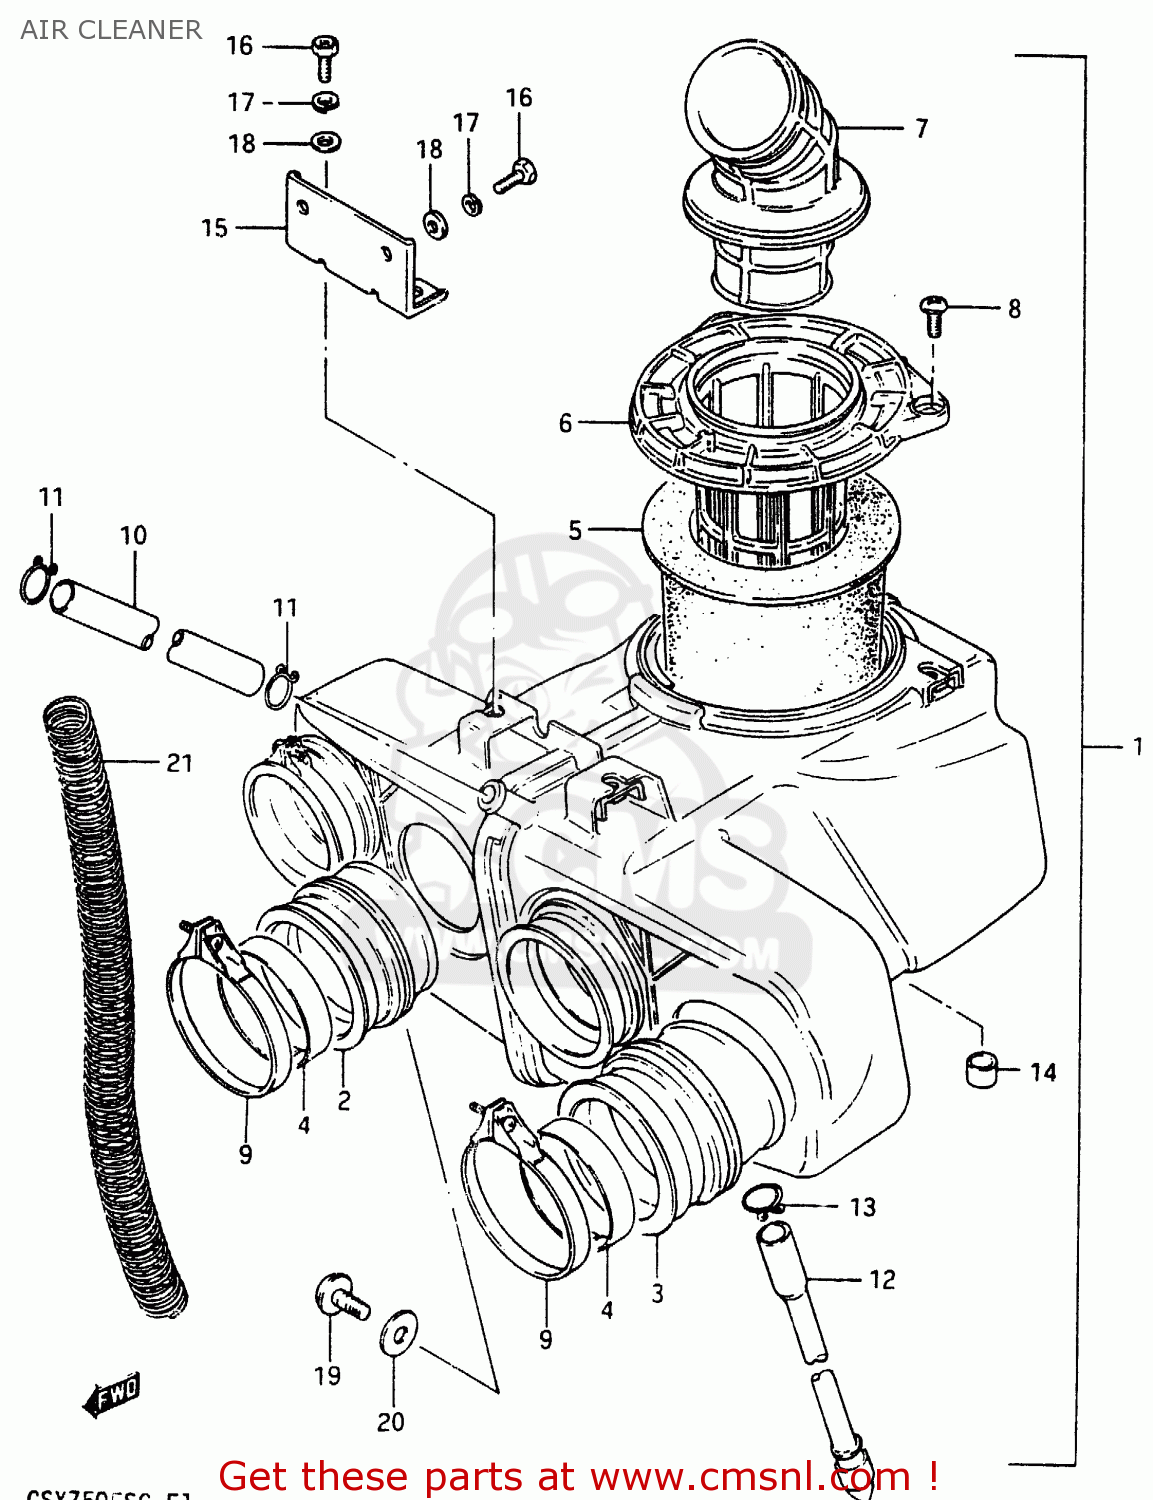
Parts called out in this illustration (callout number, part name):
1	CLEANER ASSEMBLY,AIR
2	TUBE,AIR CLEANER OUTLET
3	TUBE,AIR CLEANER OUTLET
4	RING,CARBURETOR AIR INLET HOSE
5	FILTER,AIR CLEANER
6	HOLDER,AIR FILTER
7	TUBE,AIR CLEANER INLET
8	SCREW
9	CLAMP
10	HOSE
11	CLIP
12	DRAIN TUBE
13	CLIP
14	FILTER,DRAIN
15	BRACKET,AIR CLEANER
16	SCREW(6X12)
17	LOCK WASHER
18	WASHER
19	SCREW
20	WASHER
21	SPRING
